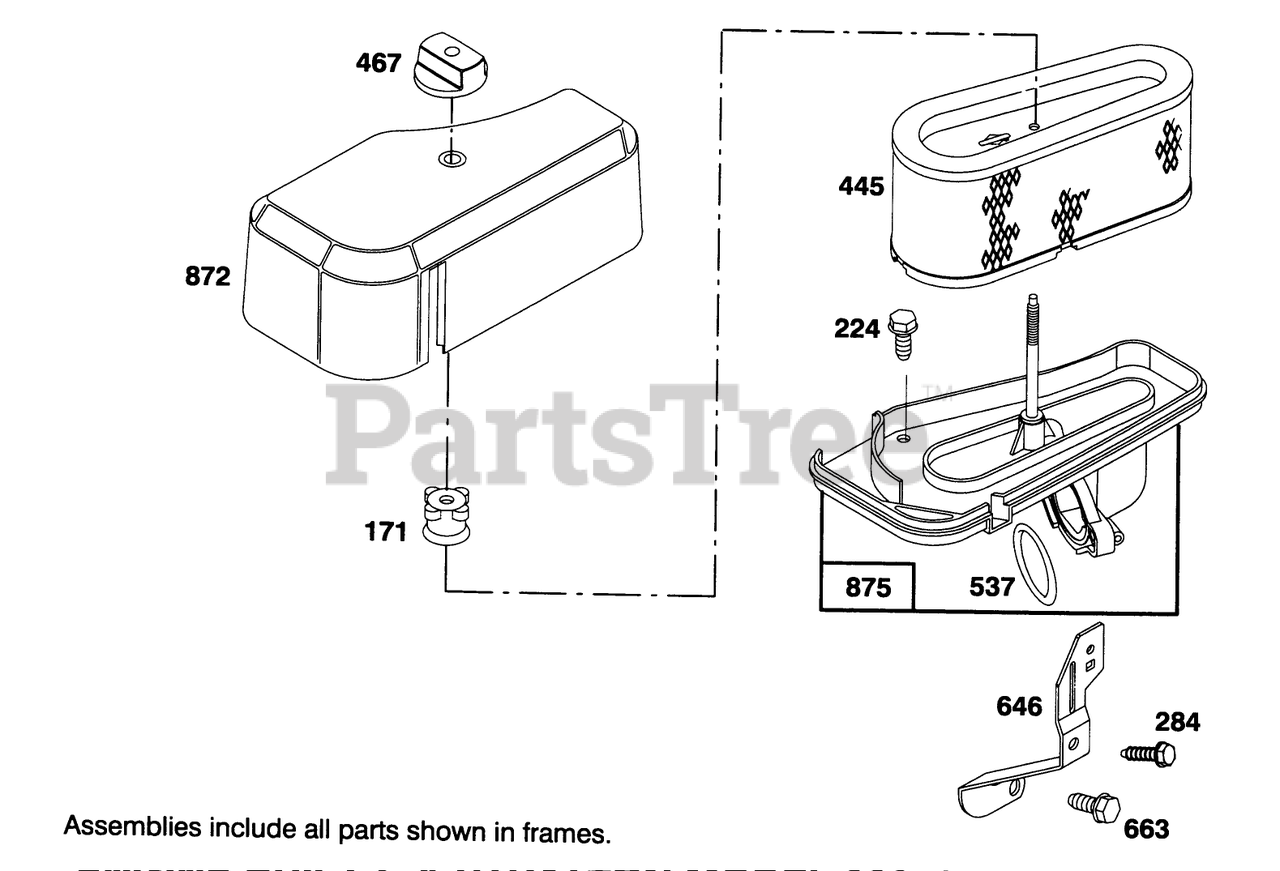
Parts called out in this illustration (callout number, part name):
224	Screw-Sem
284	Screw
445	Filter-Air
537	O-Ring
646	Brace-Air Cleaner
663	Screw
872	Cover-Air Cleaner
875	Base-Air Cleaner
